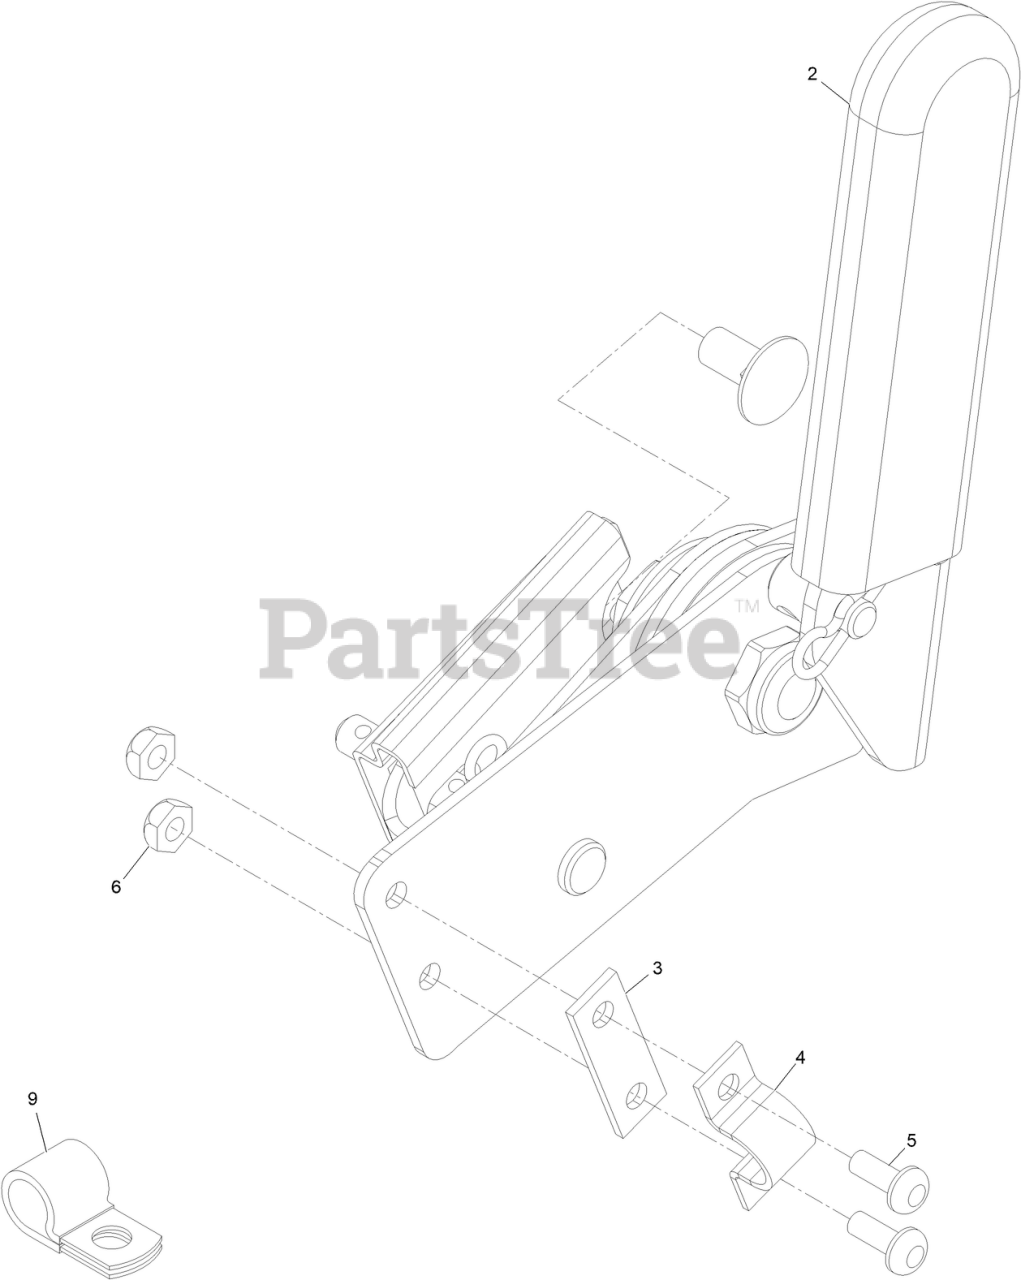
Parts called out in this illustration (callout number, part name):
2	ASM, HAND LEVER
3	SHIM,CONTROL CABLE
5	SCREW-PPH
6	NUT-LOCK, NI
9	CLIP-LOOM
